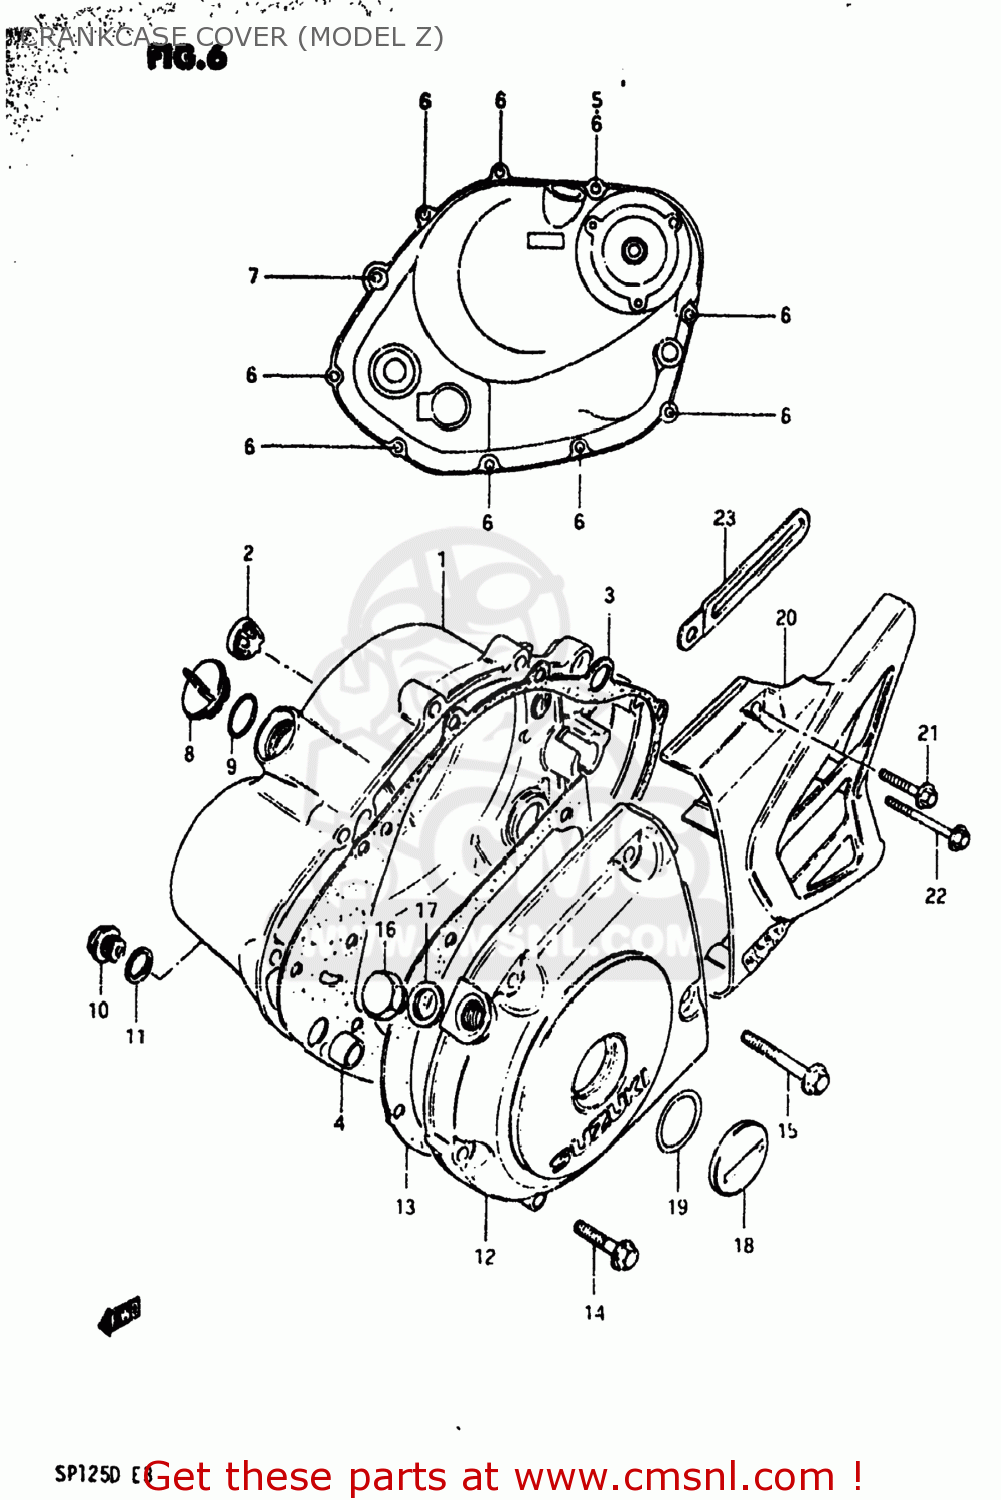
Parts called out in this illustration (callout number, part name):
1	COVER,CLUTCH
2	LENS,OIL LEVEL CHECK
3	GASKET,CLUTCH COVER (MCA)
4	PIN
5	GASKET (NAS)
6	BOLT (6X30)
7	BOLT
8	PLUG
9	O RING(D:3.1,ID:16.8)
10	PLUG (14X12)
11	GASKET(14X19.2X2) (NAS)
12	COVER,MAGNETO
13	GASKET,MAGNETO COVER (MCA)
14	BOLT (6X30)
15	BOLT (6X40)
16	PLUG,12X9
17	GASKET(12.1X16.2X3.7) (NAS)
18	PLUG
19	O RING(D:3.1,ID:22.7)
20	COVER,SPROCKET
21	BOLT
22	BOLT
23	CLAMP
